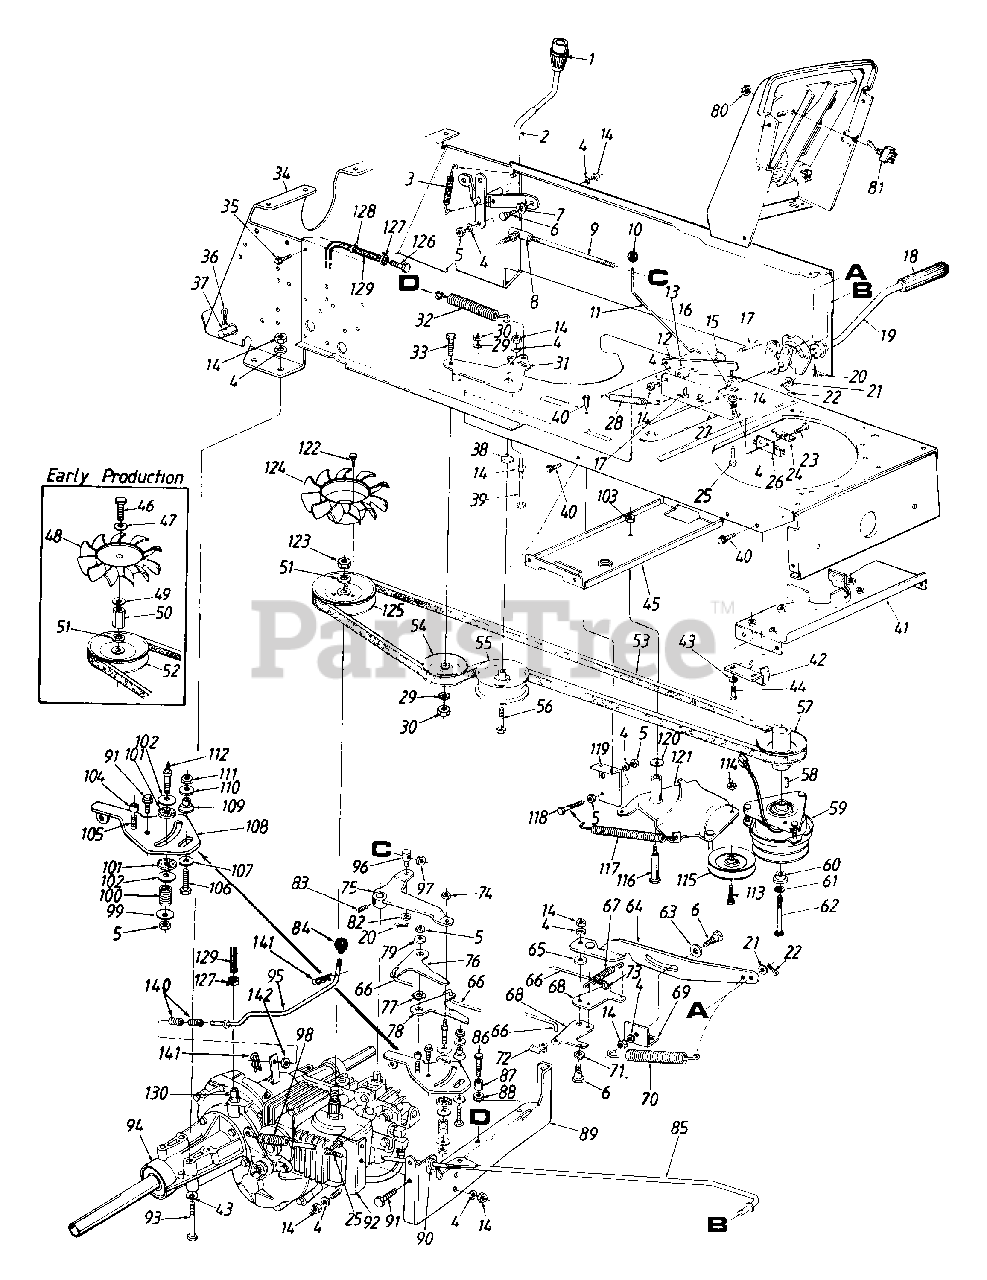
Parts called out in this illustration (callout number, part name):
1	Shift Knob
2	Speed Control Lever Ass'y.
3	Ext. Spring 2.75" Lg.
4	L-Wash. 5/16" I.D.
5	Hex Nut 5/16-24 Thd.
6	Shld. Bolt .437" Dia. x .268"
7	Spr. Wash..445" I.D. x.75" O.D.
8	Ball Joint 5/16-24 Thd.
9	Speed Selector Adjusting Rod
10	Ball Knob
11	Brake Lockout Rod
14	Hex Nut 5/16-18 Thd.
15	Shld. Spacer .27" Lg.
16	Hex Flange Bearing
17	Hex Bolt 5/16-18 x 1.25" Lg.
18	Foot Pad
21	Fl-Wash..34" I.D. x .68" O,D.
22	Cotter Pin 1/8" Dia. x 1" Lg.
23	Hex B-Tap Scr. #10 x .62" Lg.
24	Switch Plate
25	Hex Bolt 5/16-18 x .75" Lg.
26	Safety Switch (Clutch)
27	Clutch Ass'y. Mtg. Brkt.
28	Ext. Spring 2.51" Lg.
29	L-Wash. 3/8" I.D.
30	Hex Nut 3/8-16 Thd.
31	Idler Brkt.
32	Ext. Spring 4.75" Lg.
33	Hex Bolt 3/8-16 x 1.5" Lg.
36	Hitch Pin
37	Hitch Rod
38	Shld. Spacer .625" I.D.
39	Hex Bolt 5/16-18 x 2.75" Lg.
40	Hex Wash. Hd. TT-Tap Scr. 1/4-20 x .5" Lg.
41	Belt Guard Brkt.
44	Hex Cap Scr. 5/16-18 x .75" Lg. (Gr. 5)
45	Deck Idler Support Brkt.
46	Hex Cap Bolt 9/16-18 x.5" Lg.
47	Bell-Wash..567" I.D. x 1.125" O.D.
49	Fl-Wash. 9/16" I.D. x 1.75" O.D.
50	Fan Adapter Nut 9/16-18 Thd.
51	Int. L-Wash. 9/16" I.D.
52	Input Pulley
53	"V"-Belt
54	Idler Pulley
55	Fl-Idler Pulley
56	Hex Bolt 3/8-16 x 2" Lg. (Gr. 8)
57	Engine Pulley
58	Sq.-Key 1/4" x 1" Lg.
59	Electric Clutch
60	Shld. Spacer
61	L-Wash. 7/16" I.D.
62	Hex Cap Bolt 7/16-20 x 3.75" Lg.
63	Fl-Wash..531" I.D. x 1.25" O.D.
64	Neutral Return Link Ass'y.
65	Fl-Wash..344" I.D. x 1.12" O.D. (Hdn)
66	Connecting Rod
67	Ext. Spring 2.5" Lg.
68	Balancer Brkt.
69	Bracket
70	Ext. Spring 3.94" Lg.
71	Spr.-Wash..445" I.D. x .75" O.D.
72	Rod End Clevis Clip - R.H.
73	Rod End Clevis Clip - L.H.
74	Hex Ins. L-Nut 3/8-24 Thd.
75	Pintle Bracket Ass'y.
76	Flat Scissors
77	Spr. Wash..625" I.D. x.885" O.D.
78	Offset Scissors
79	Fl-Wash..344" I.D. x 1" O.D. (Hdn)
80	Hex Nut 1/2-27 Thd.
81	Toggle Switch
82	Fl-Wash..406" I.D. x .75" O.D.
83	Hex Socket Set Screw
84	Ball Knob
85	Brake Rod Ass'y.
86	Hex Wash. Hd. Scr. 1/4-20 x 1.5" Lg.
87	Spacer .39" Lg.
88	Hex Nut 1/4-20 Thd. (Gr. 5)
91	Hex Wash. Hd. TT-Tap Scr. 5/16-18 x .62" Lg.
94	Transaxle
95	Bypass Rod
96	Ferrule 3/8-24 Thd.
97	Hex Jam Nut 3/8-24 Thd.
98	Ext. Spring 4.01" Lg.
99	Fl-Wash..3/2" I.D. x.75" O.D.
100	Comp. Spring 1.19" Lg.
101	Friction Washer
102	Bell-Wash..40" I.D. x 1.13" O.D.
103	Hex Cent. L-Nut 3/8-16 Thd.
104	Spacer
105	Rib Neck Bolt 5/16-18 x .62" Lg.
106	Hex Bolt 1/4-28 x 1" Lg. (Gr. 5)
107	Fl-Wash..26" I.D. x .72" O.D.
108	Scissors Mtg. Brkt.
109	Centering Gauge Spacer
110	Bell-Wash. 1/4" I.D.
111	Hex Nut 1/4-28 Thd.
112	Friction Disc Stud
113	Hex Bolt 3/8-24 x 1.5" Lg.
114	Hex Cent. L-Nut 3/8-24 Thd.
115	V-Belt Idler
116	Shld Bolt .498" Dia. x 2.05
117	Ext. Spring 4" Lg.
118	Hex Bolt 5/16-24 x 1.75" Lg.
119	Parking Brake Mtg. Brkt.
120	Bell-Wash..38" I.D. x.88" O.D.
121	Idler Brkt. Deck Ass'y.
122	Hex Wash. Hd. Tap Scr. #12 x 3/8" Lg.
123	Hex Jam Nut 9/16-18 Thd.
124	Fan
125	Input Pulley
126	Plastic Vent
127	Rubber Grommet
128	Cable Tie
129	Hose 1/2" I.D. x 18" Lg.
130	Hose Fitting
140	Comp. Spring 1" Lg.
141	Hairpin Clip
142	Fl-Wash. 1/4" I.D.
